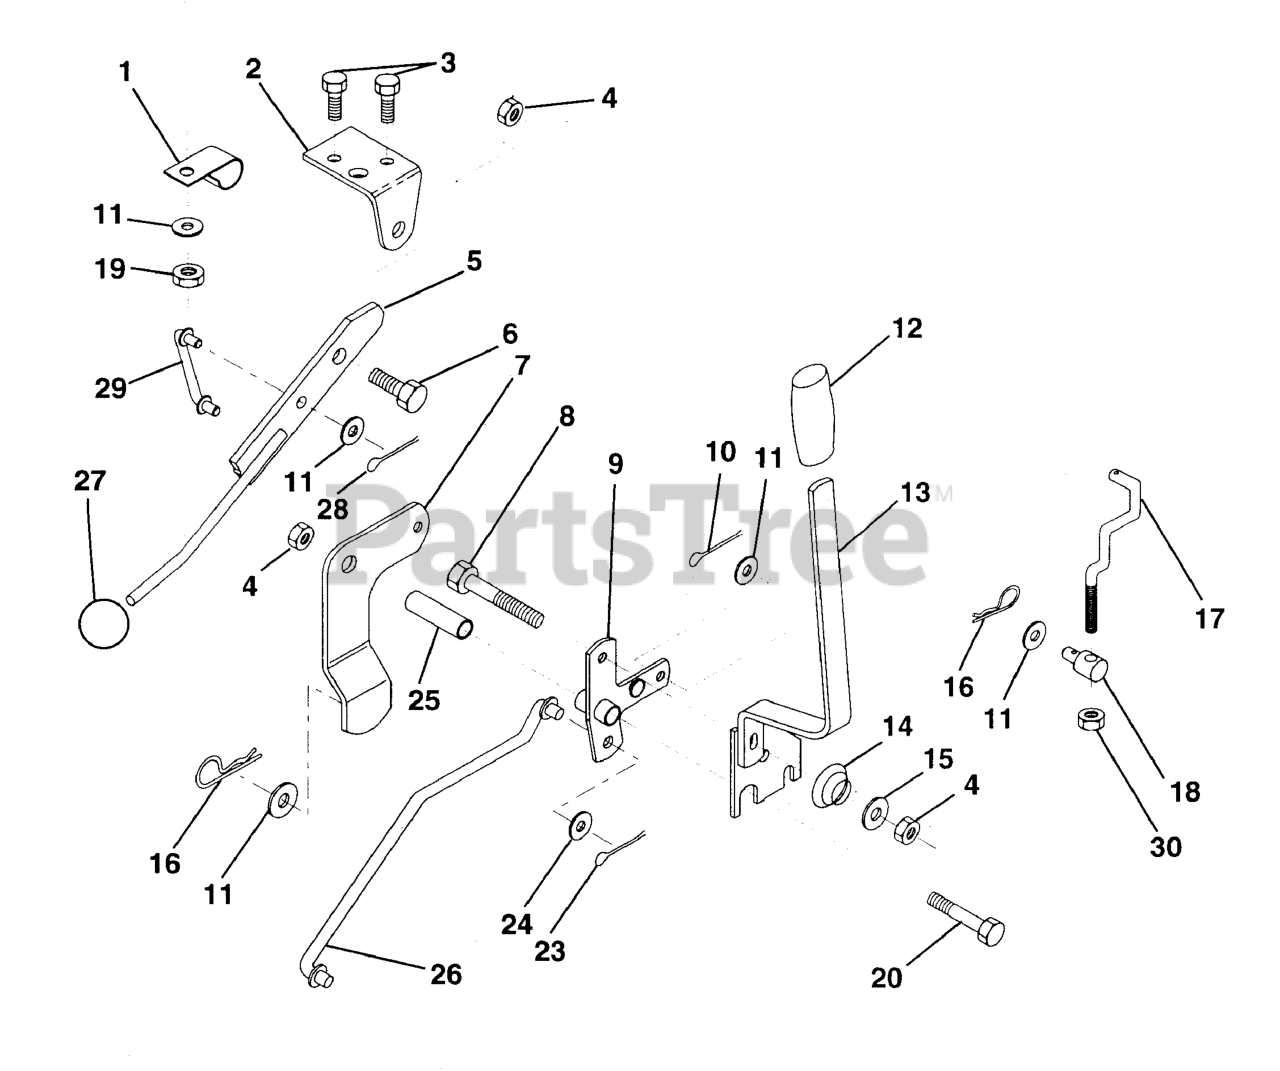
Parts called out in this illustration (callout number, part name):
1	CLIP,INSULATOR
2	BRKT CLUTCH
3	BOLT
4	NUT
5	CLUTCH LEVER ASSY
6	BOLT, SHOULDER LT
7	ASSEMBLY MOWER CLUTCH ARM
9	BELLCRANK,LIFT
10	COTTER PIN
11	WASHER
12	HANDLE GRIP
13	LIFT HANDLE ASSY
14	SPRING COMPRESSIO
15	WASHER T
16	SPRING TI
17	LINK LIFT FRT
18	TRUNION
19	NUT.CROWNLOCK.1/4
23	PIN COTTER
24	WASHER
25	TUBE SPACER
26	ROD,MOWER LIFT
27	KNOB T (3/8 HOLE)
28	COTTER PIN
29	LINK MOWER CLUTCH
30	NUT
